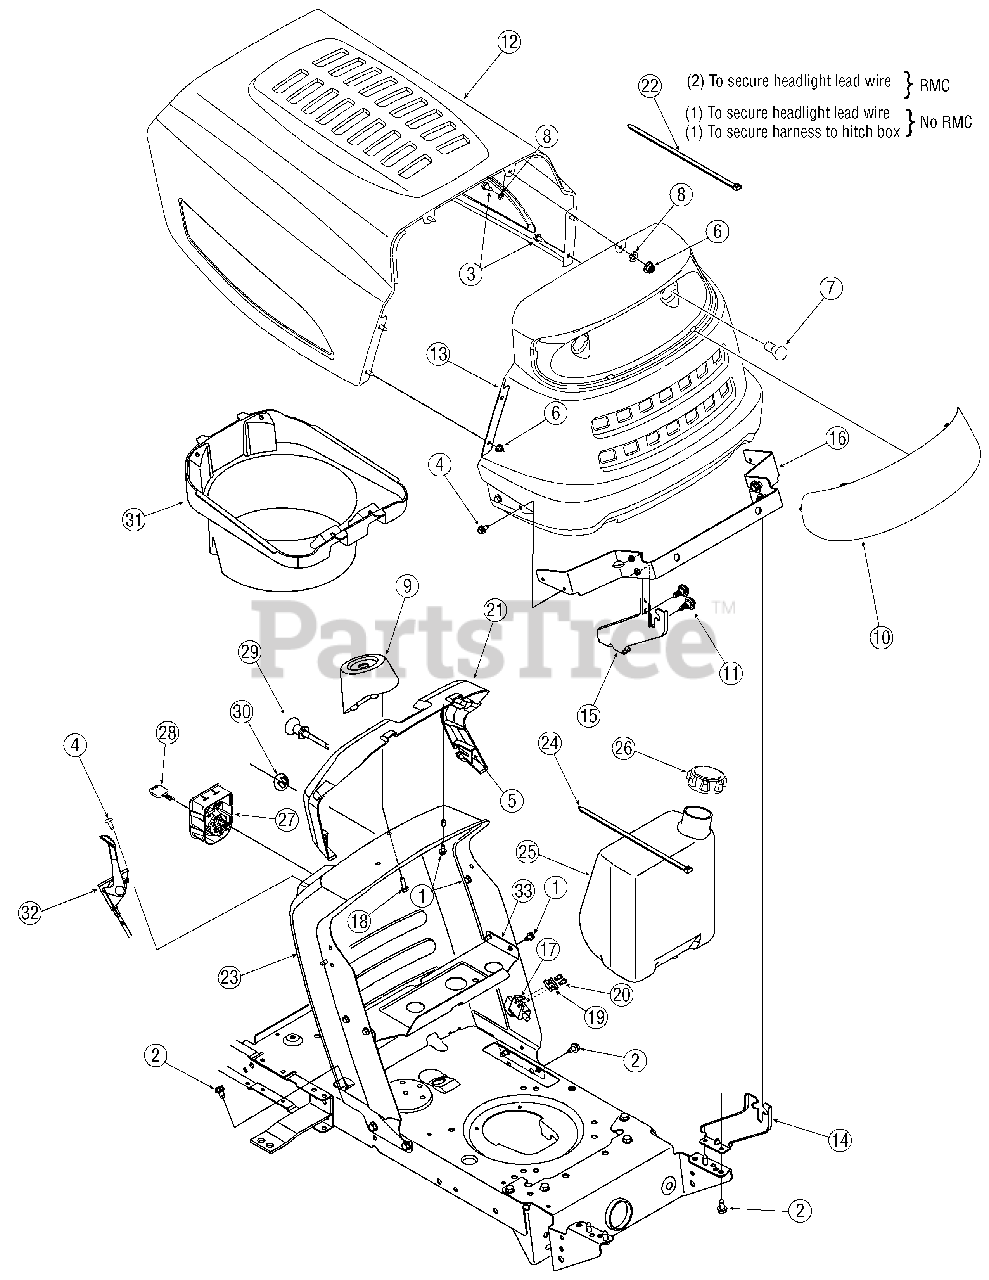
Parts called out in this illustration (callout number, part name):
1	Screw, 1/4-20, 0.500
2	Screw, 5/16-18, 0.625
3	Screw, 1/4-20, .620, Gr5
4	Screw, 1/4-20, .500
5	Nut, 1/4-20, Speed U-type
6	Nut, Flange Lock, 1/4-20,
7	Headlamp, 12V
8	Washer, Flat, .265 x .938
9	Support, Steering
10	Lens
11	Screw, Shoulder, .43 x.29,
18	Screw, 1/4-15, 0.750
19	Switch Plate
20	Pop Rivet with RMC
21	Collar, Dash
24	Cable Tie, 34.75
25	Fuel Tank, 1.5 gal.
26	Fuel Tank Cap
27	Module, Ignition Switch (RMC)
27	Igntion, Switch (No RMC)
28	Key
29	Choke Control, 37.5"
31	Plenum (Single Cylinder
32	Throttle/Choke Control, 25" (Single Cylinder Engine)
